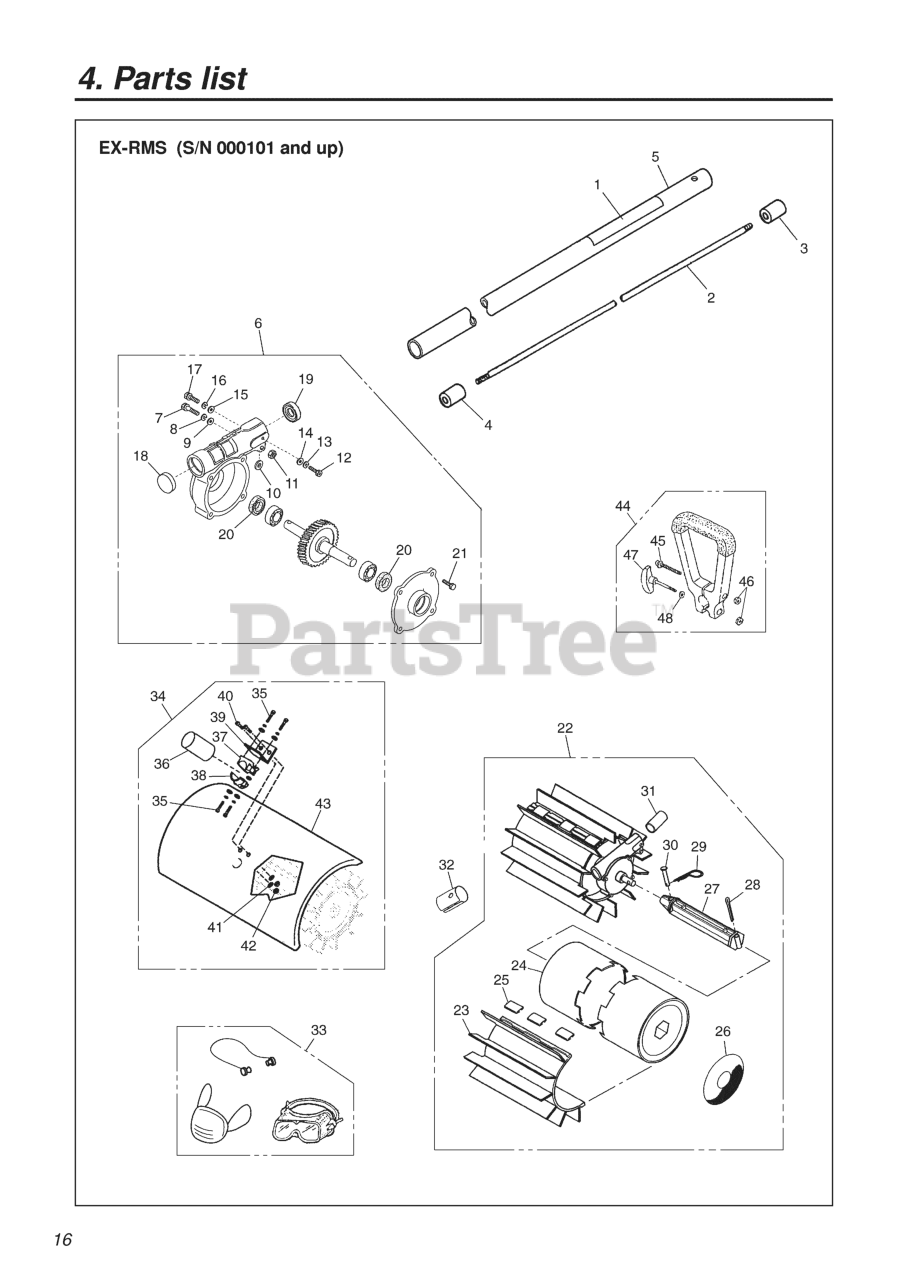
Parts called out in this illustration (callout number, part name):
1	PIPE COMP
2	SHAFT
3	JOINT, SHAFT (RPLS -12240)
4	SPACER
5	PLATE-NAME
7	BOLT, M6 x 30
8	SPRING WASHER
9	WASHER, FLAT
10	WASHER, FLAT
11	NUT, M6 X 5
12	BOLT, M5 x 12
13	WASHER, SPRING M4 x 1.3
16	WASHER, SPRING M4 x 1.3
17	SCREW
18	PLUG, HOUSING
21	SCREW
22	SWEEPER ASSY
25	CLIP, BELT
26	LABEL, REDMAX
27	AXLE, DRUM (RPLS -33016)
28	PIN, COTTER
29	PIN, HITCH
30	PIN, CLEVIS (RPLS -33018)
31	PROTECTOR, TUBE
33	SAFETY KIT
34	DEBRIS SHIELD ASSEMBLY
37	BRACKET, HANDLE
38	CAP, LOWER
39	BRACKET, SHIELD
44	HANDLE ASSY (RPLS 99909-33009)
